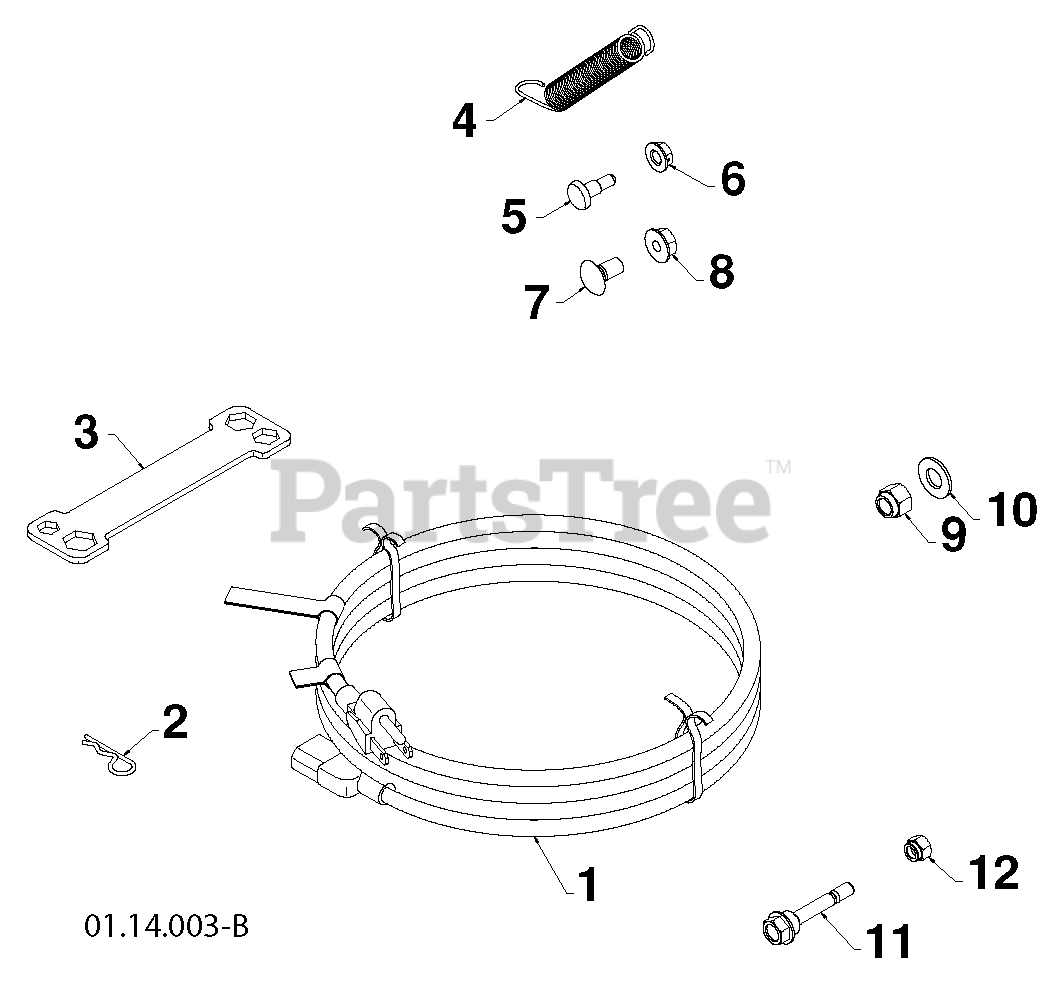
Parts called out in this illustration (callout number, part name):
1	CORD.ELECTRIC.10FT.120V.SNOW
2	SPRING RETAINER
3	WRENCH.SNOWTHROWER.ZINC.YZ
4	SPRING.DEFLECTOR.REM.CHUTE
5	BOLT, SHOULDER
6	NUT.HEX.FLANGE.1/4
8	NUT.LOCK.5/16-18
9	NUT
11	BOLT.SHOULDER.SHEAR.1/4-20.
12	LOCKNUT.NYLOC.1/4-20
